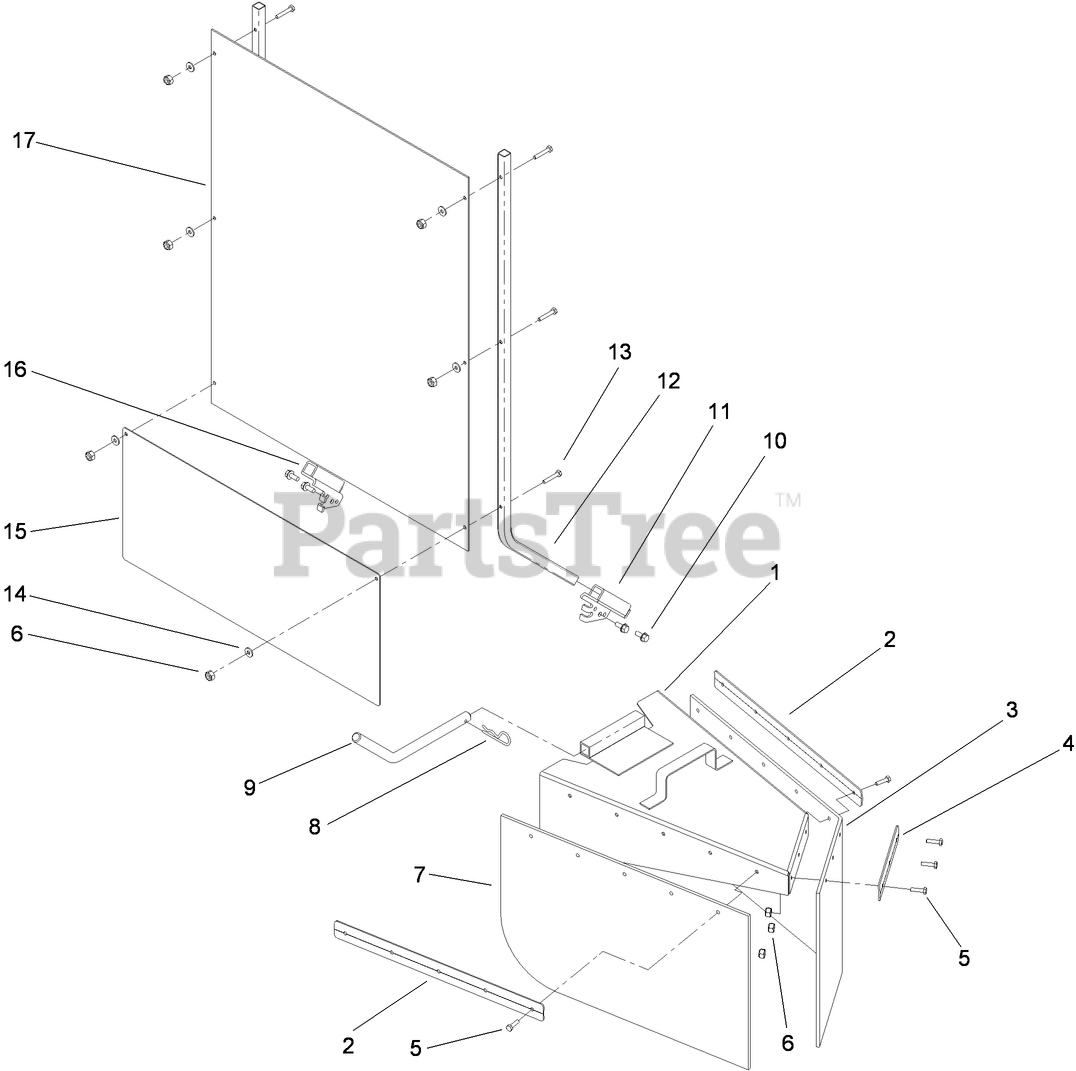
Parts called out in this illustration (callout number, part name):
1	CHIPPER GUARD ASM
2	CLAMP-SKIRT
3	GUARD-SKIRT, REAR
4	CLAMP-SKIRT
5	SCREW-HH
6	NUT-HEX
7	GUARD-SKIRT, FRONT
8	PIN-HAIR
9	PIN-HINGE
10	SCREW-HWHTF
11	BRACKET-SUPPORT, LH
12	SUPPORT-SHIELD
13	SCREW-HH
14	WASHER-FLAT
15	SKIRT-PROTECTOR
16	BRACKET-SUPPORT, RH
17	SHIELD-LEXAN
